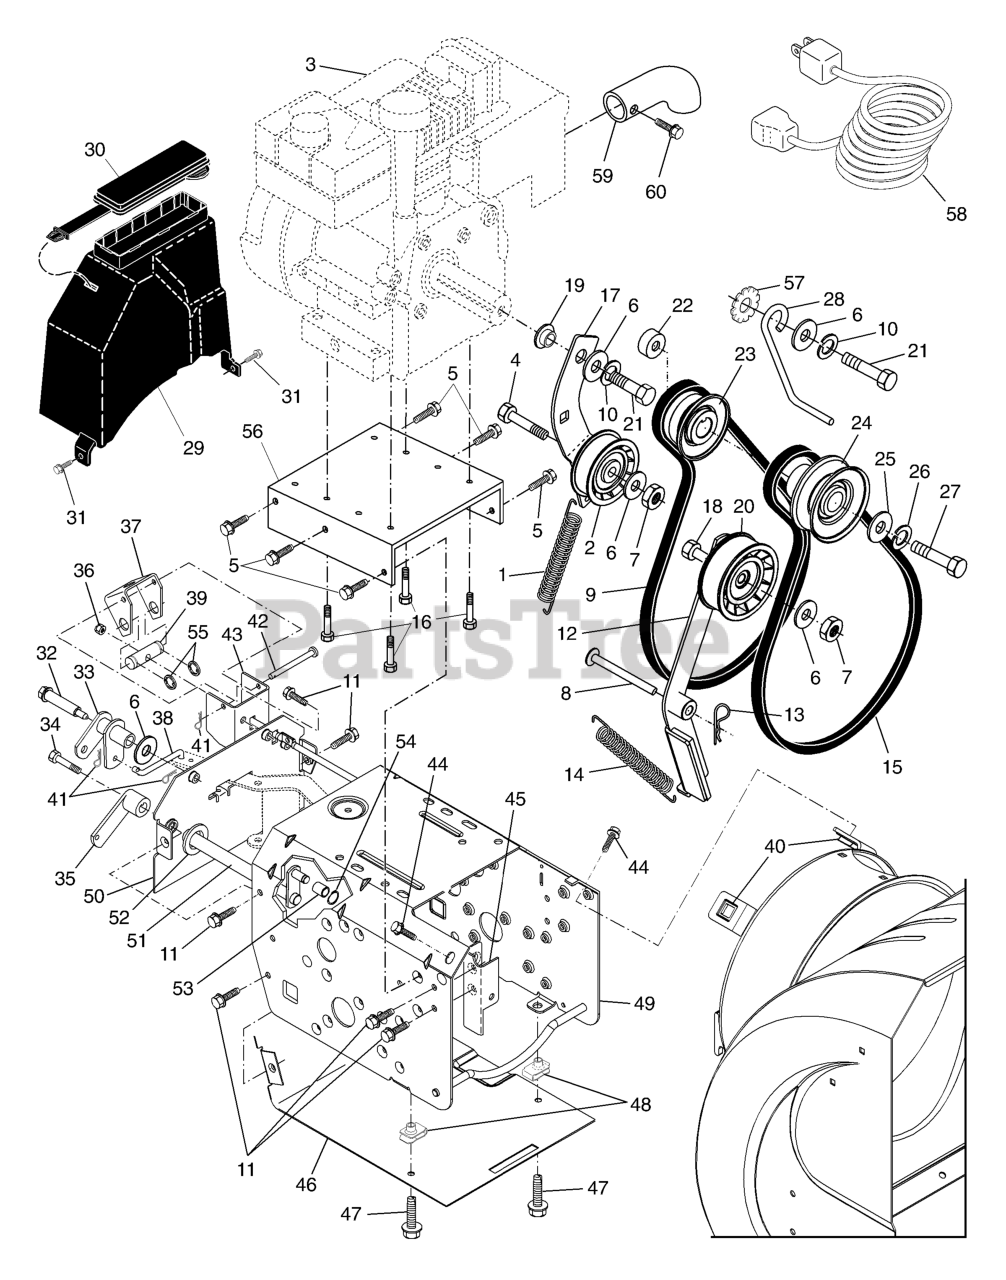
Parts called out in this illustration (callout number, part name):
1	RP SPRING, TRACTION IDLER
2	PULLEY.W/SPACER.2.25
4	BOLT.5/16-18X1-1/4 FULL.THREAD
5	SELF-TAPPING SCREW 5/16-18X3/4
6	STEEL WASHER
7	NUT.CENTERLOCK.5/16-
8	PIN, IDLER PIVOT
9	V-BELT, TRACTION DRIVE
10	WASHER.LOCK.HVY.HLCL.SPR.5/16
11	Screw, Hex Head 5/16-18 x 1/2
12	ARM ASSEMBLY, IMPELLER IDLER
13	RETAINER CLIP PM
14	SPRING, BRAKE
15	V-BELT, IMPELLER DRIVE
16	BOLT, ENGINE, 3/8-16
17	IDLER ARM
18	HEX BOLT
19	RP BUSHING, IDLER PIVOT
20	PULLEY.W/SPACER.2.75
22	SPACER, ENGINE PULLEY
23	PULLEY,ENGINE TRACTION DRIVE
24	PULLEY, ENGINE IMPELLER DRIVE
26	LOCKWASHER
27	SCREW, HEX HD 3/8-24 X 1-3/8
28	BELT.GUIDE.RH
29	COVER.ASM.BELT/STORAGE
30	COVER.STORAGE.SNOW
31	SCREW
32	BOLT, SHOULDER 5/16-18
33	BELLCRANK SHIFTER
35	ARM CONTROL.PM
36	NUT.71038.31-18.HEX.NYLOCK
37	BRACKET, PIVOT
38	LINK, SPEED CONTROL
39	TRUNNION, TRACTION
40	NUT, CAGE 3/8-16
41	RETAINER CLIP
42	PIN, PIVOT BRACKET
44	Screw, Hex Head
45	BRACKET, IDLER PIVOT
46	PAN, FRAME BOTTOM
47	Screw, Hex Head 5/16-18 x 3/4
48	NUT.SPEED.5/16-18
49	FRAME ASSEMBLY
50	PLATE, FRAME END
51	CONTROL SHAFT WELDMENT
52	THRUST WASHER
53	ROLLER, ACTUATOR
54	RING.CRESENT
55	RETAINING RING LT
56	PLATE, ENGINE MOUNTING
57	WASHER EXT TOOTH LOCK 5/16
58	CORD.EXTENSION.B&S.695613.
59	DEFLECTOR, MUFFLER
